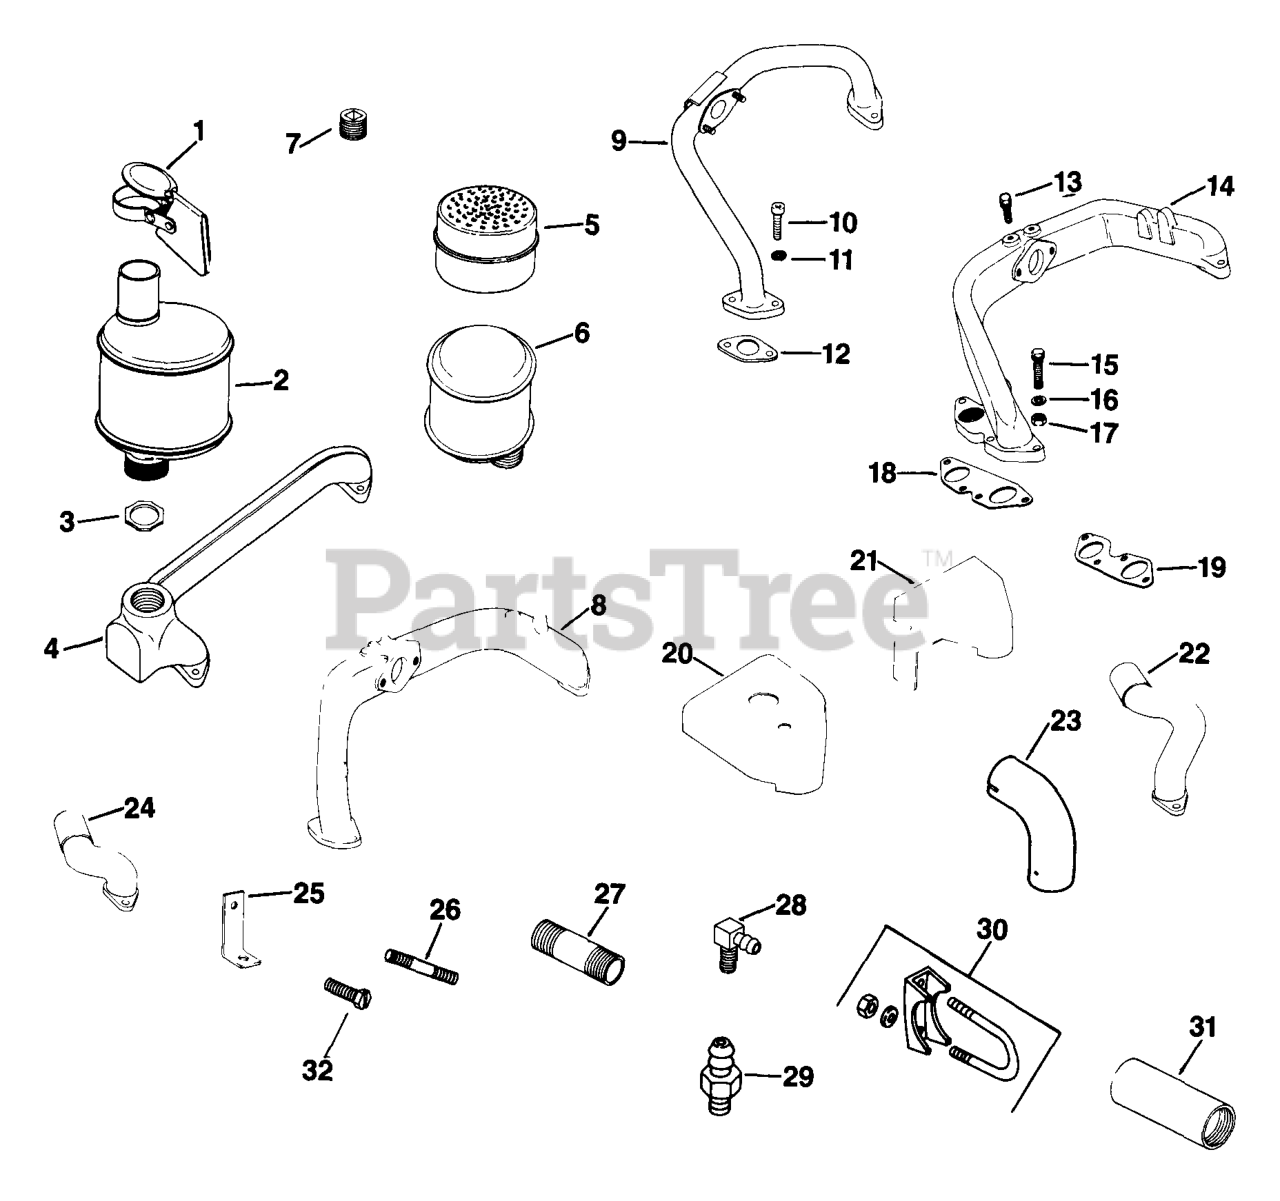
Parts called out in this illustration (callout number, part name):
9	MANIFOLD - DISCONTINUED
10	SCREW, HEX SOCKET HEAD CAP USE 25 086 89-S
12	GASKET - DISCONTINUED
25	STRAP, LIFTING
